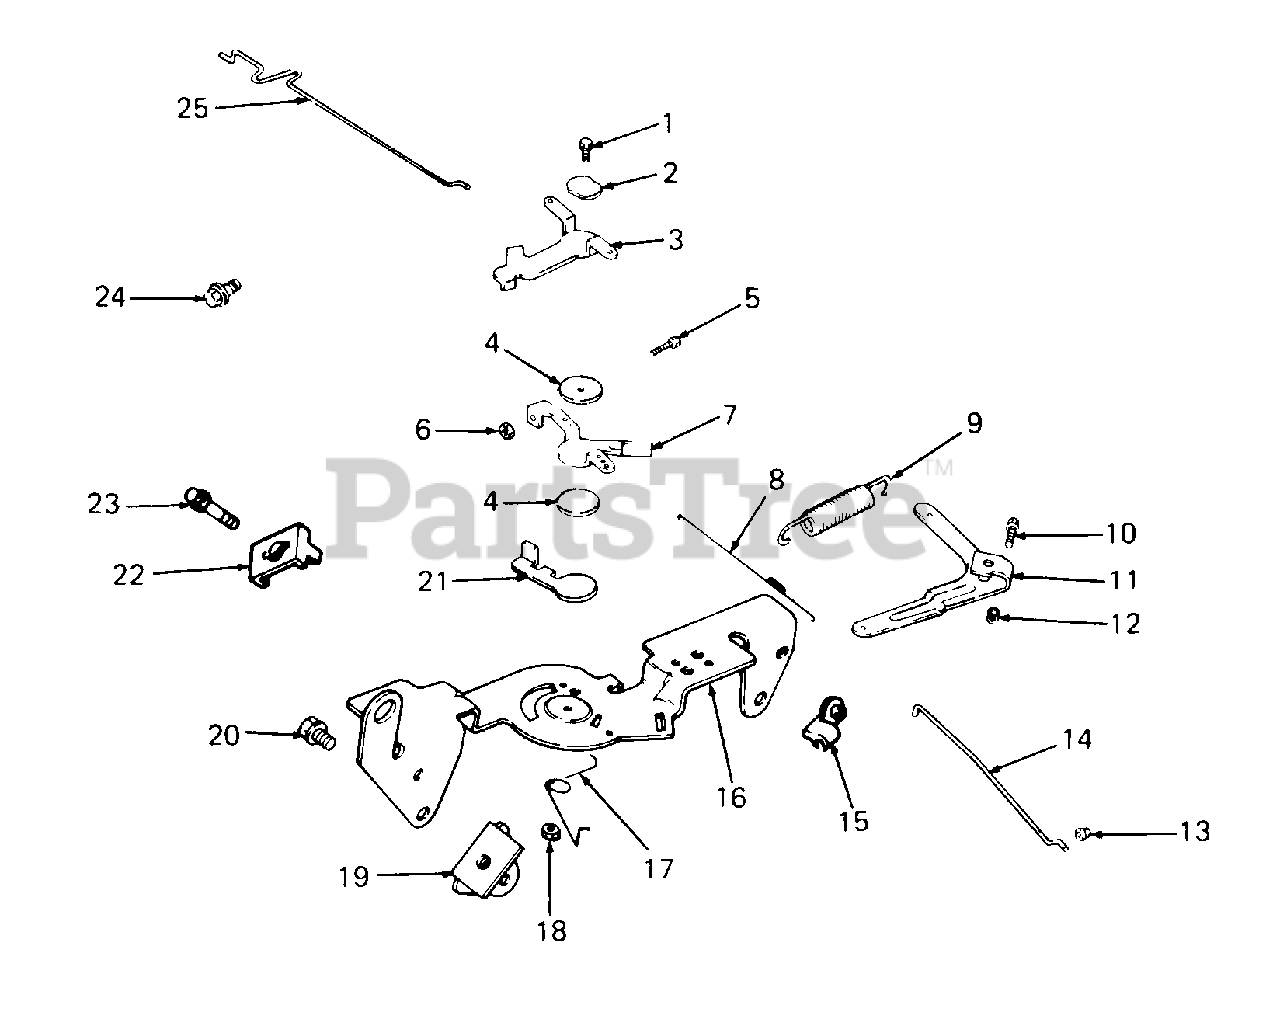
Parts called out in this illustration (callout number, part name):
1	Screw, M6 X 0.8 X 20
2	Washer, Spring
3	Lever, Choke
5	Screw, M4 X 0.7 X 27.9
6	Nut
7	Lever, Throttle Control
8	Spring, Linkage
9	Spring, Governor
10	Screw, M6 X 1.0 X 25
11	Lever, Governor
12	Nut, M6 X 1.0
13	Bushing, Linkage Retaining
14	Linkage, Throttle
15	Bushing, Linkage Retaining
16	Bracket, Control
17	Spring, Choke Return
18	Nut, M6 x 0.8
19	Bracket, Support
20	Screw, M6 X 1.0 X 16
21	Lever, Throttle Actuator
22	Clamp, Cable
23	Screw, M6 X 0.8 X 16
24	Screw, M6 X 0.8 X 10
25	Linkage, Choke
